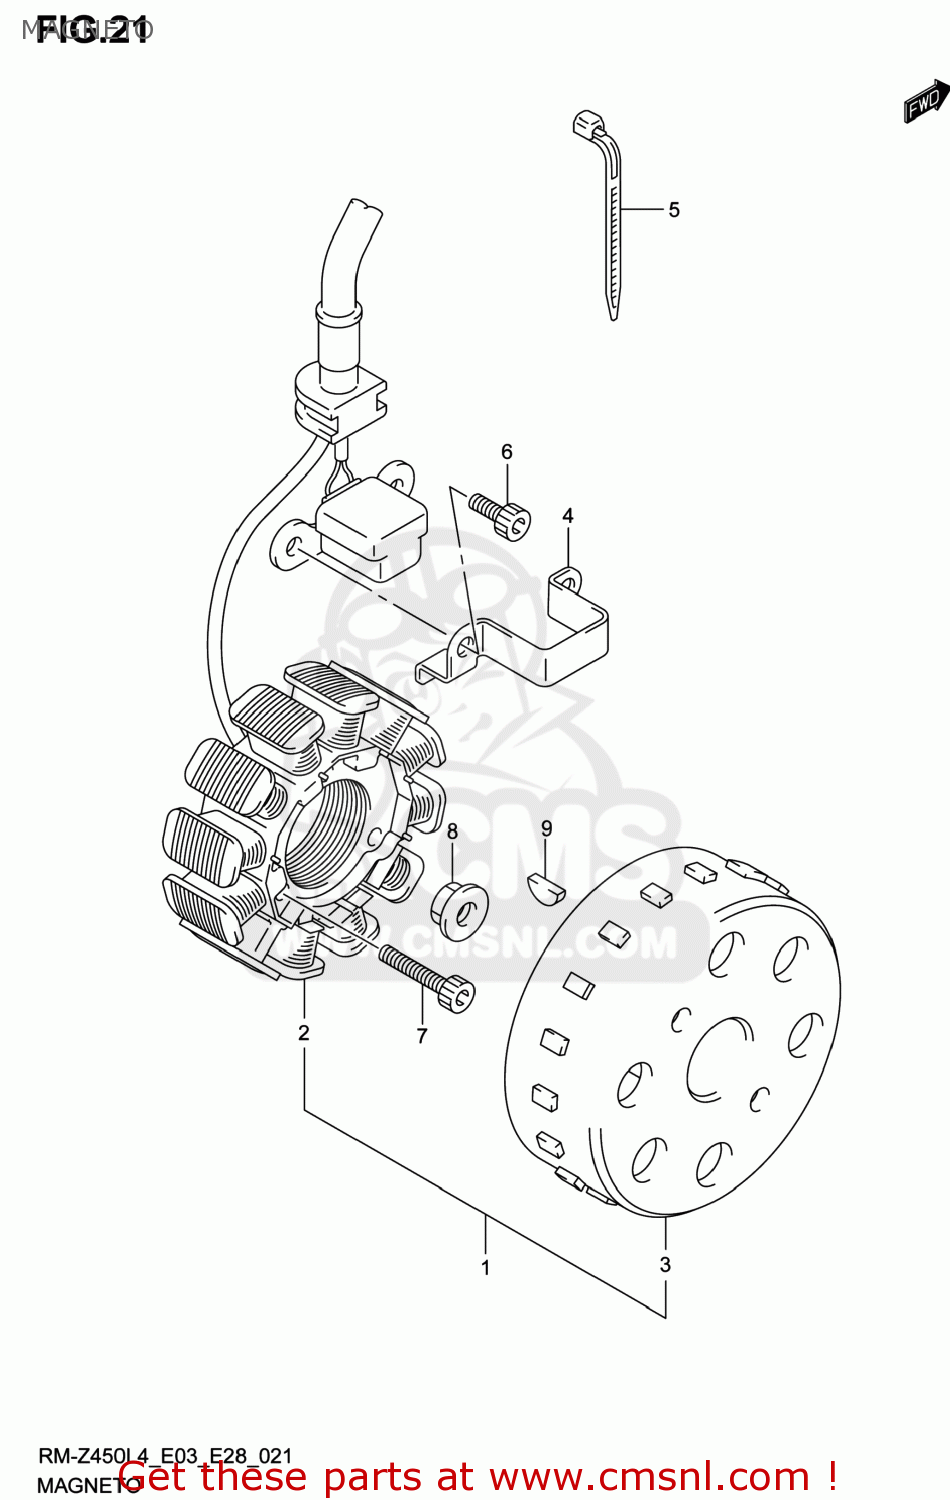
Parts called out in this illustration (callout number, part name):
1	MAGNETO ASSY
2	STARTER ASSY
3	ROTOR ASSY
4	CLAMP,MAGNETO LEAD
5	CLAMP(L:165)
6	BOLT
7	BOLT
8	NUT
9	KEY
